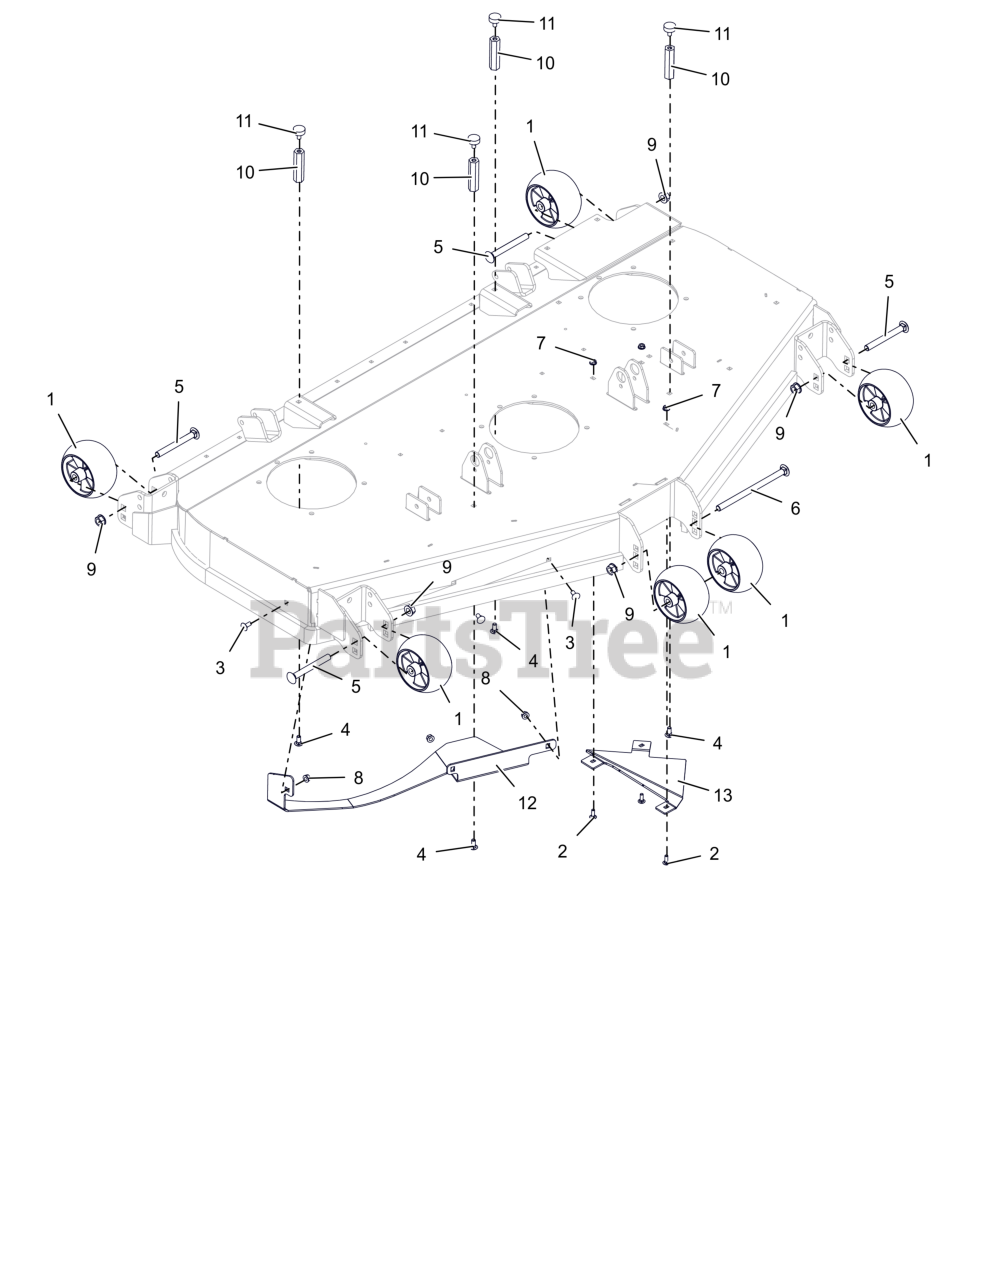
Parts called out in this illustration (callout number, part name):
1	WHEEL, ANTI SCALP - 5X3 CTR W/RIBS
2	BLT, RHSN .25-20X.750 G5 ZCC
3	BLT, RHSSN.31-18X.750 G5 ZCC
4	BLT, RHSN .31-18X.75 G5 ZCC LT
5	BOLT, RHNS .50-13X4.50 G5 ZCC NS
6	BOLT, RHNS .50-13X8.00 G5 ZCC NS
7	NUT-LK-CTR-FLG .25-20 ZC120
8	NUT,LK-CTR-FLG .31-18 GF ZCC
9	NUT-LK-CTR-FLG .500-13 GG ZCC
10	NUT, COUPLING .31-18 X 3.00
11	BUMPER, RUBBER
12	DEFLECTOR, BAFFLE BOLT-IN (ORANGE)
13	BAFFLE, INSERT TRIANGLULAR (ORANGE)
